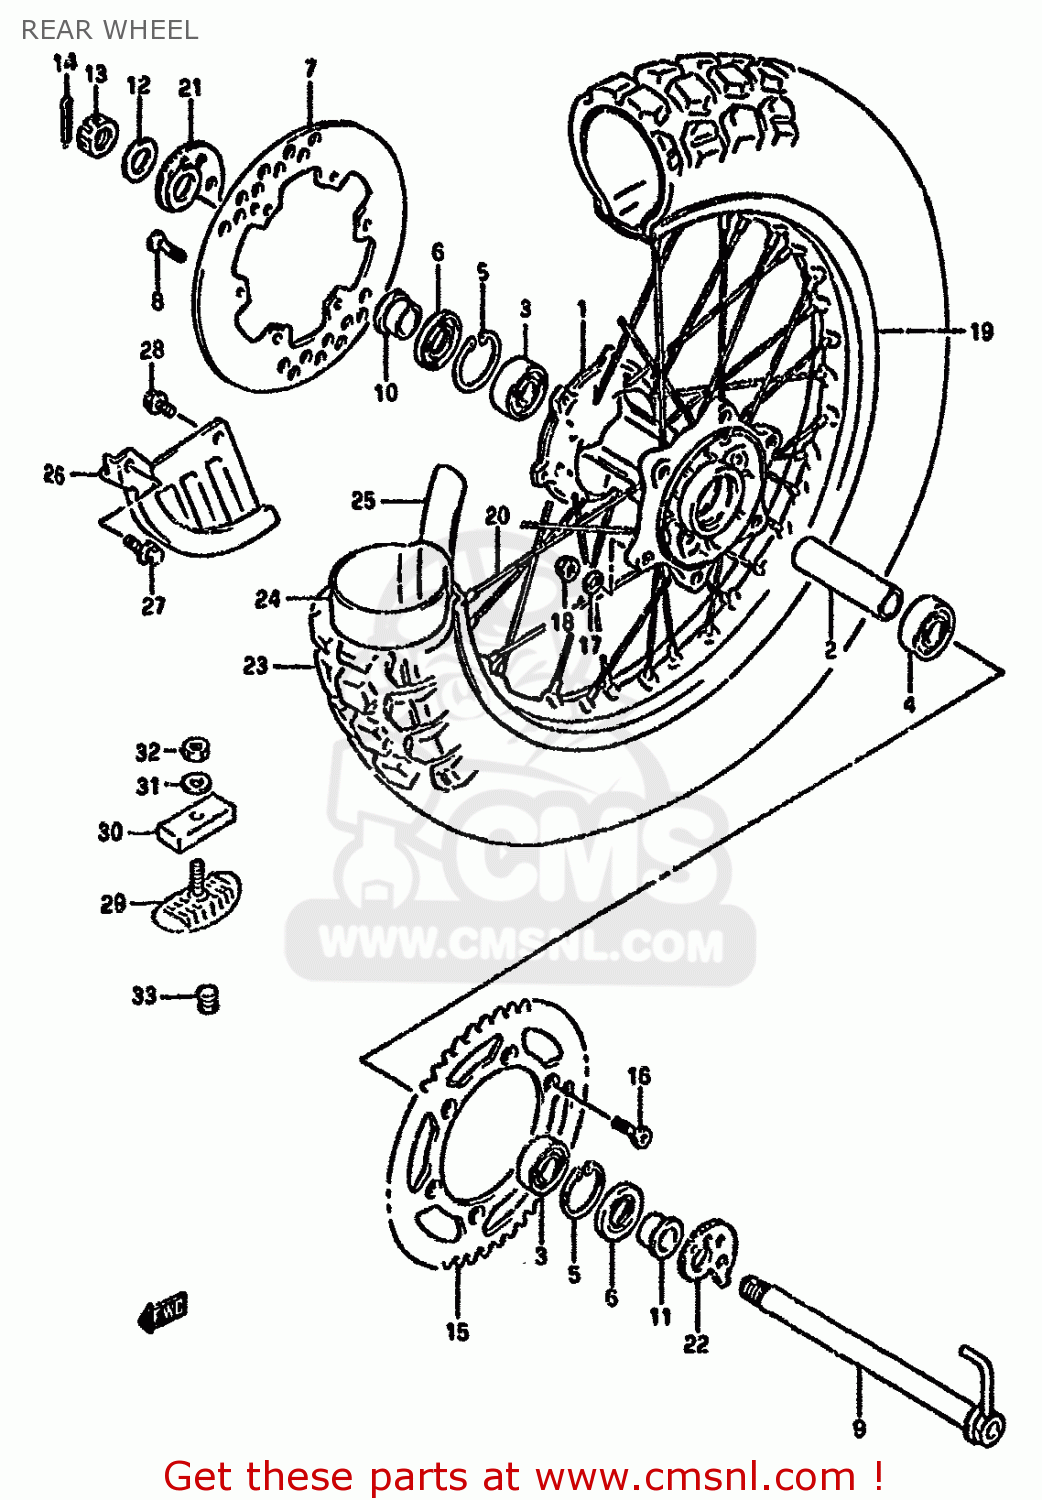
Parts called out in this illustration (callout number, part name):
1	HUB,RR
2	SPACER,RR HUB BEARING
3	BEARING WHEEL REAR(20X47X14)
4	BALL BEARING
5	CIRCLIP,14MM
6	SEAL,OIL(26X47X5)
7	DISC,RR BRAKE
8	SCREW,BRAKE DISC
9	AXLE,RR
10	SPACER,RR AXLE,R
11	SPACER,RR AXLE,L
12	WASHER(19X32X3.2)
13	NUT
14	PIN,COTTER
15	SPROCKET,REAR
16	SCREW(8X33.5)
17	WASHER
18	NUT
19	RIM,REAR WHEEL (2.15X18)(A
20	SPOKE SET,REAR WHEEL
21	ADJUSTER,CHAIN,R
22	ADJUSTER,CHAIN,R
23	TIRE,REAR 110/100-18
24	TUBE ASSEMBLY,WHEEL,INNER
25	PROTECTOR,INNER TUBE
26	COVER,REAR DISC
27	BOLT
28	BOLT
29	STOPPER,BEAD(2.15)
30	CUSHION,BEAD STOPPER
31	WASHER
32	NUT
33	CAP(OD:12)
